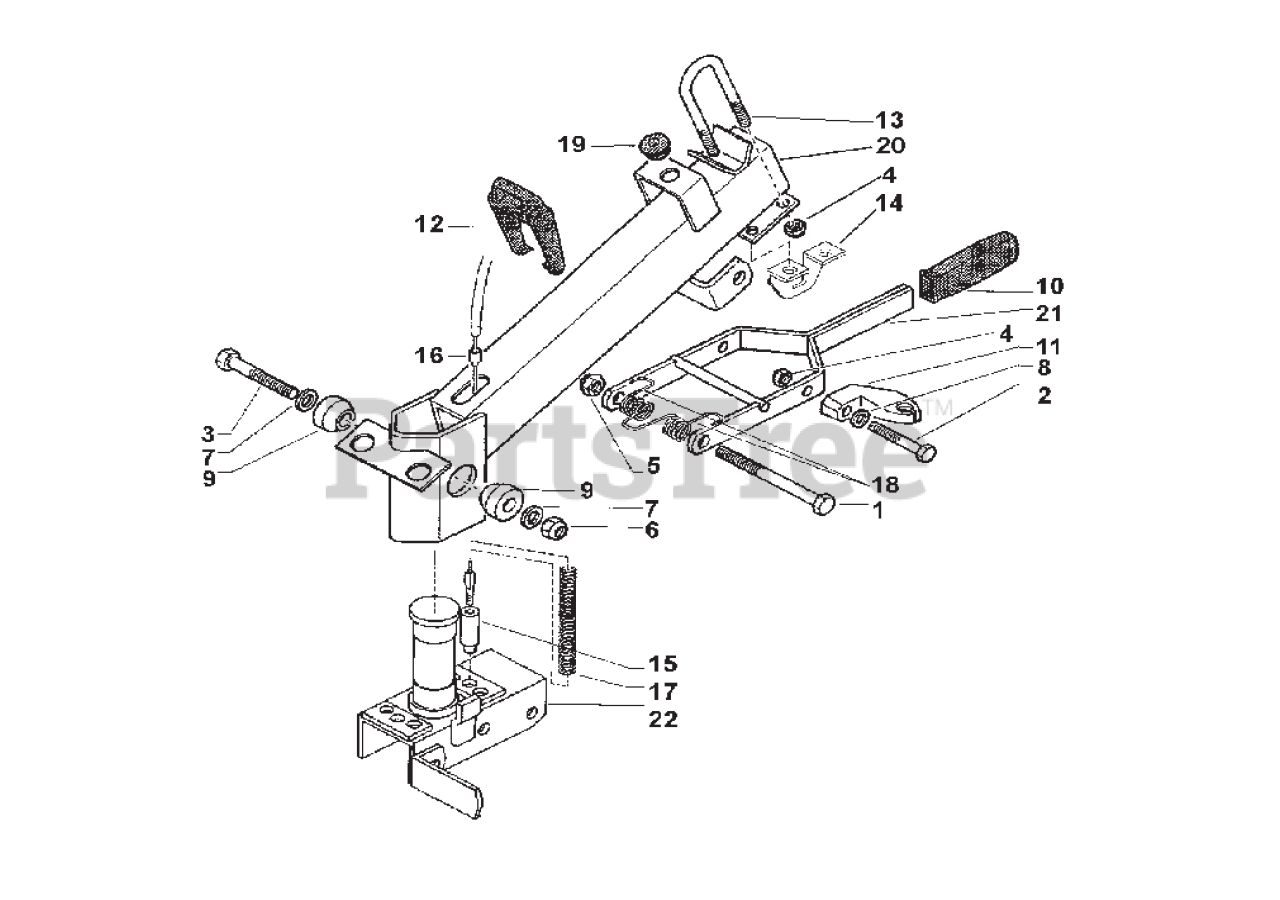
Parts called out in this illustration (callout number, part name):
1	CAP SCREW, M10X110
2	CAP SCREW, M8X35
3	CAP SCREW, M12X80
4	LOCK NUT, M8
5	LOCK NUT, M10
6	LOCK NUT, M12 DEFORMED
7	SPRING
8	WASHER LOCK, M8.4
9	WEDGE
11	SUPPORT, CONTROL ROD
12	CABLE GUIDE
13	U BOLT
14	BRACKET
16	SHEATH END
17	SPRING, STEERING COLUMN
18	HANDLEBAR RELEASE SPRING
19	SUPPORT CAP
20	STEERING COLUMN
21	LEVER, HANDLEBAR SELECTION
22	SUPPORT
